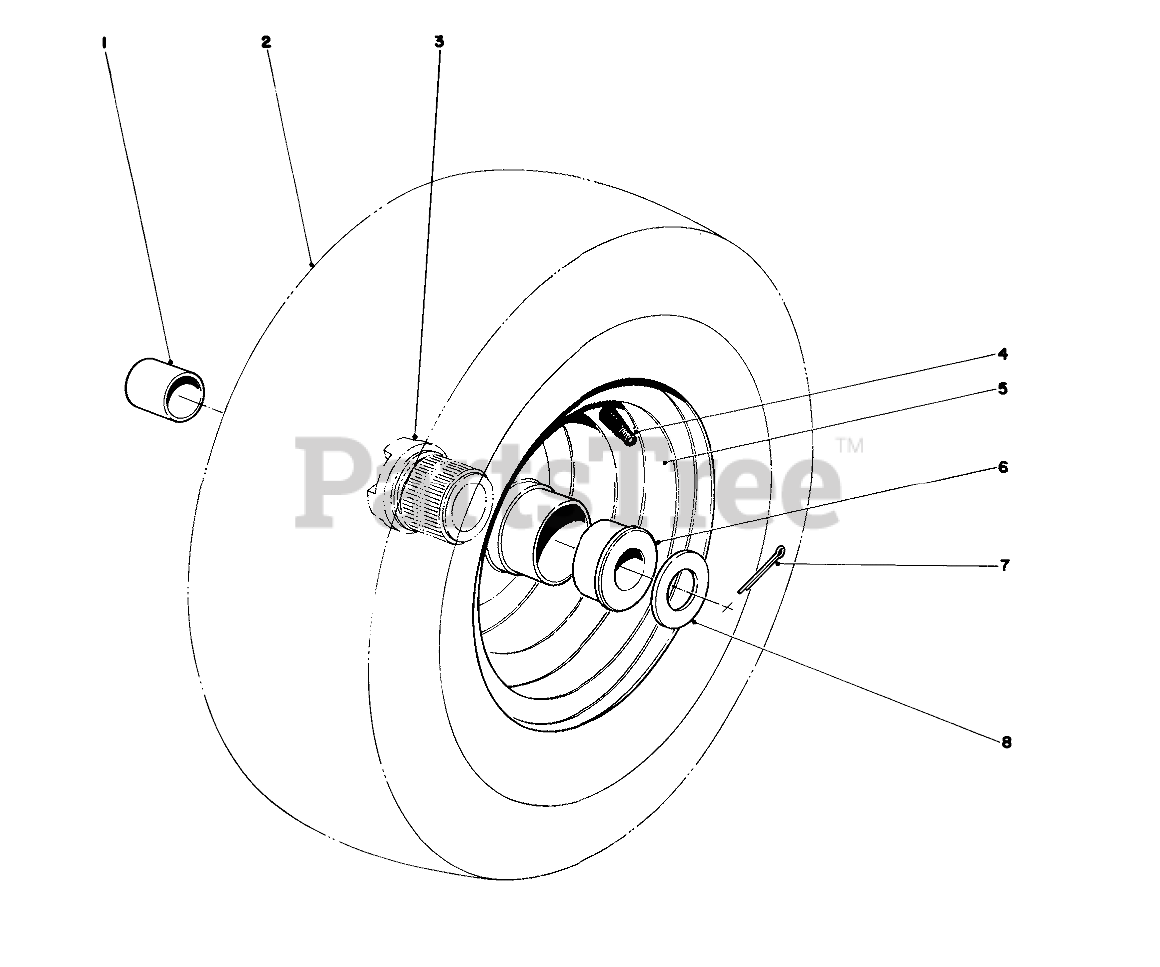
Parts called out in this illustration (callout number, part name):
1	.877ID X .750LG BSHG
3	JAW HUB
4	STEM-VALVE
6	Bushing
7	PIN-COTTER
8	WASHER-THRUST
